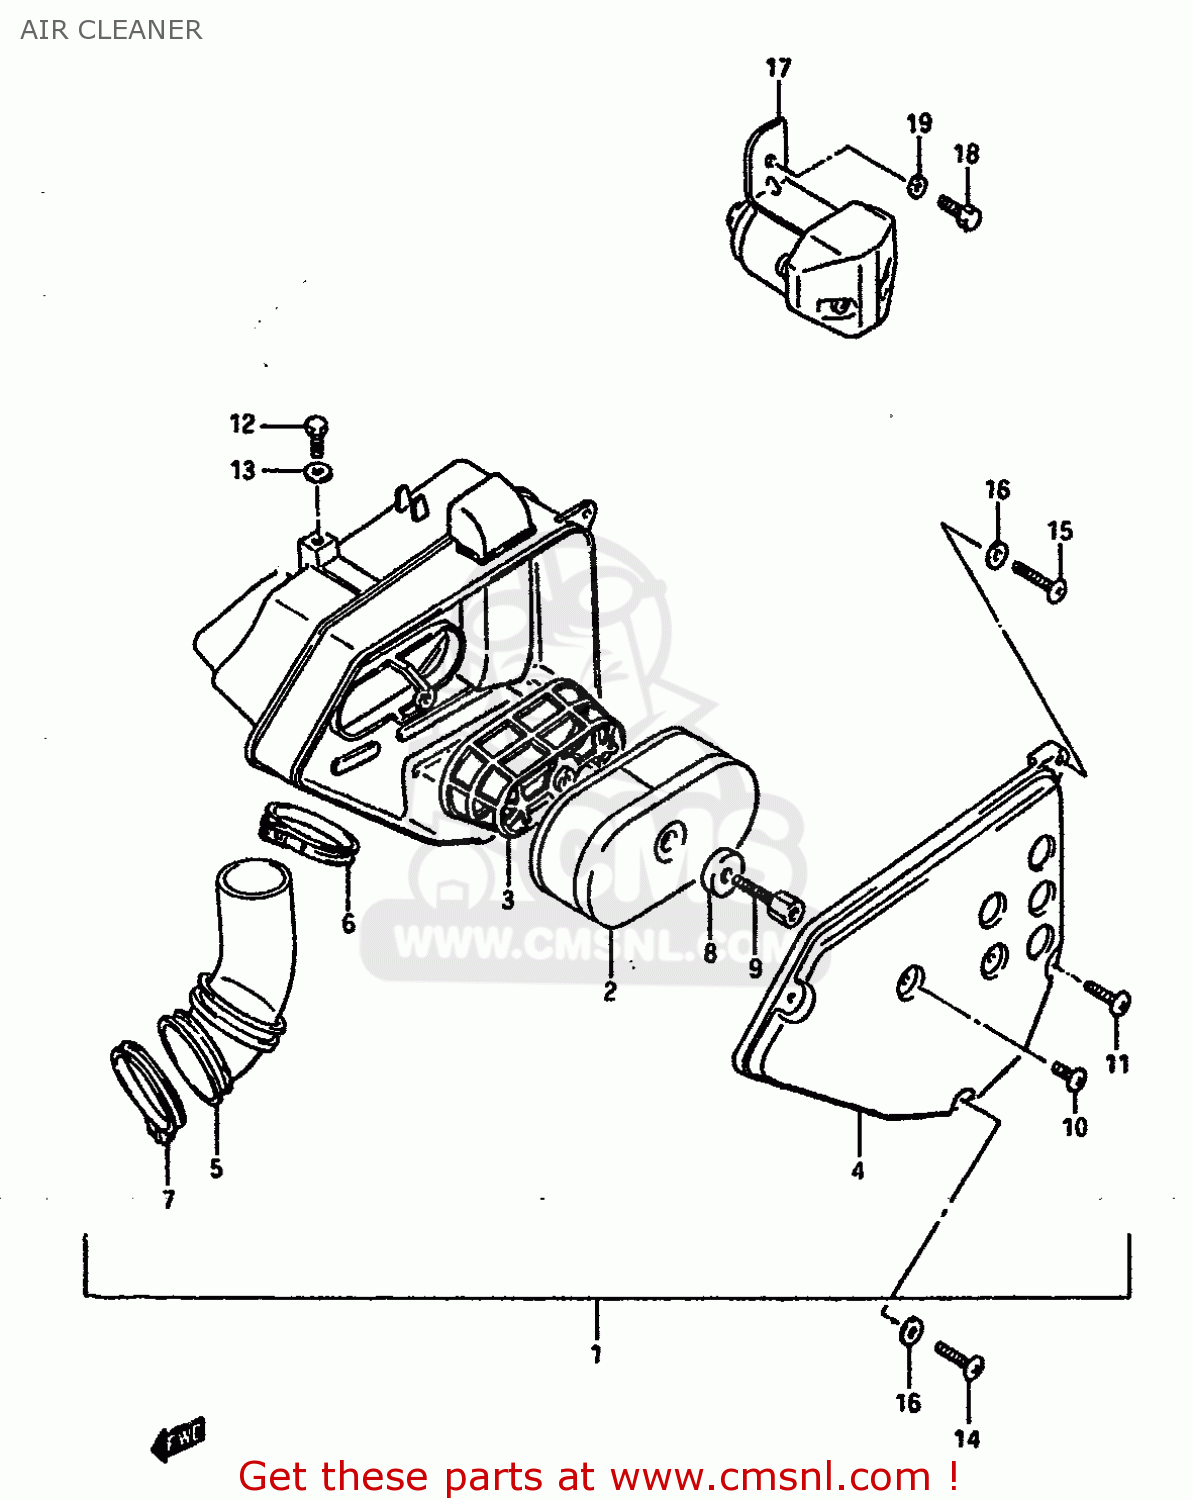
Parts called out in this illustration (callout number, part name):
1	CLEANER ASSY,AIR
2	FILTER
3	HOLDER
4	CAP
5	TUBE,OUTLET
6	CLAMP
7	CLAMP
8	WASHER,AIR CLEANER
9	BOLT
10	SCREW
11	SCREW(6X25)
12	BOLT
13	WASHER(6.5X16X1.2)
14	SCREW(6X25)
15	SCREW
16	WASHER
17	COMPENSATOR ASSY,ALTITUDE
18	BOLT
19	WASHER,LOCK
